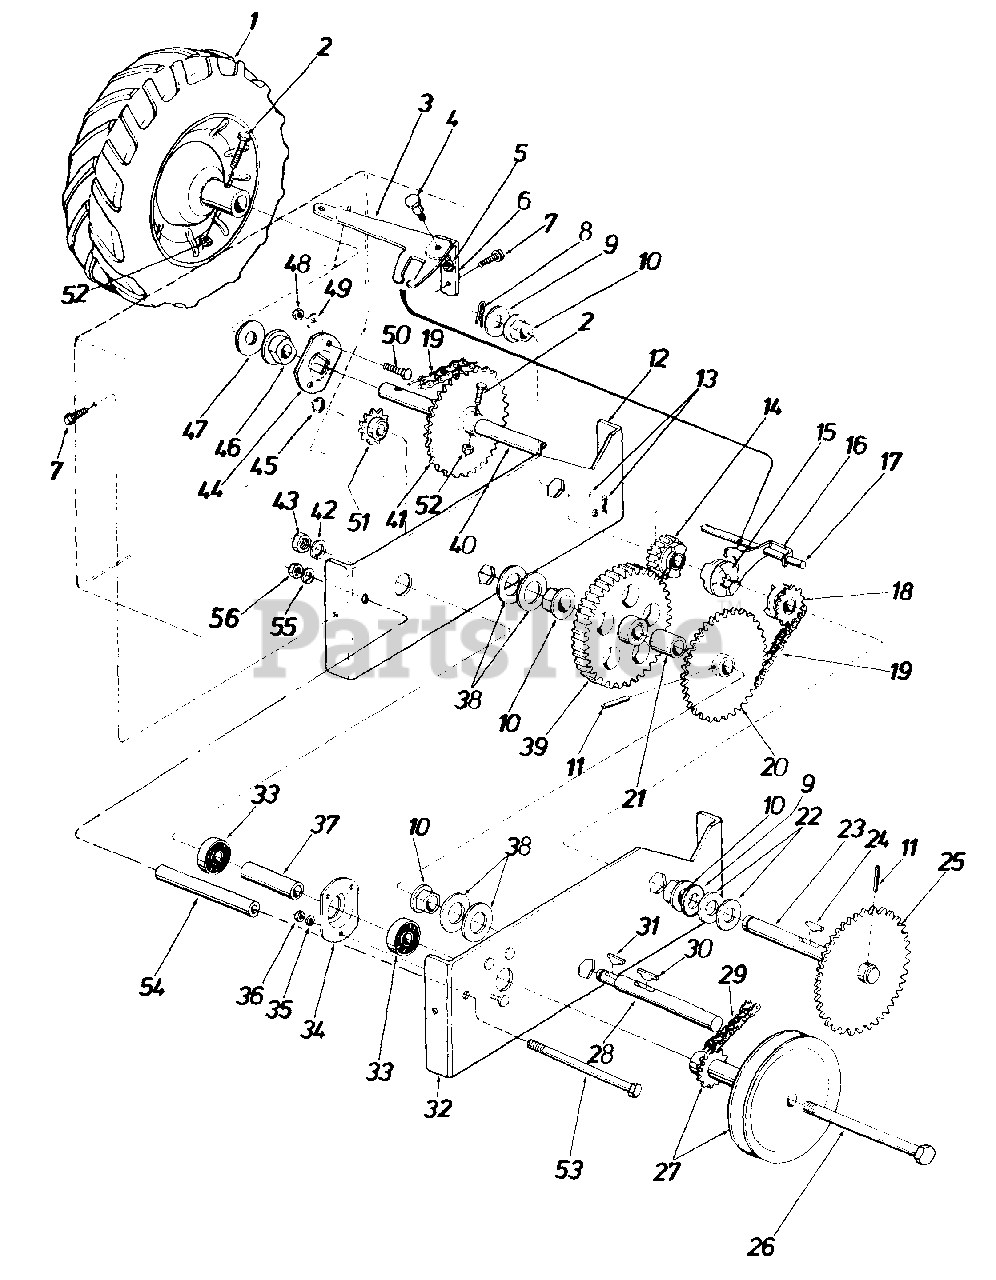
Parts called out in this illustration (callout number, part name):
1	Wheel Ass'y. - Comp. 10.0 x 2.75 - R.H.
2	Hex Scr. 5/16-24 x 1.75" Lg. H.T.
3	Shifting Bracket
4	Shld. Scr. .438" Dia. x .180 Lg.
5	Hex Cent. L-Nut 5/16-18
6	Shifting Bracket Support
7	Hex Wash. Hd. Self-Tap Scr. 5/16-24 x .50
8	Cotter Pin 3/32 Dia. x 1.00" Lg.
9	Fl-Wash. .64 I.D. x 1.25 O.D. x .060
10	Hex Flange Brg. .63 I.D.
11	H-Spring Pin Spiral 1/4" Dia. x 1.50 Lg.
12	Drive Housing Bracket - R.H.
13	Internal Cotter Pin 5/16" Dia.
14	Spur Gear - 21 Teeth
15	Clutch Collar
16	Shifting Yoke
18	Sprocket - 10 Teeth
19	#41 Chain - 1/2" Pitch x 33 Links
20	28 Teeth - Sprocket Hub Ass'y.
21	Spacer - .62 I.D. x .88 O.D. x 1.030
22	Fl-Wash. .64 I.D. x 1.25 O.D. x .100
23	Shifting Shaft
24	Hi-Pro Key 3/16 x 3/4" Dia. x 1.062
25	32 Teeth Sprocket Hub Ass'y.
26	Hex Scr. 1/2-20 x 5.50" Lg.
27	5.25" O.D. Pulley with 9 Teeth Sprocket
29	#41 Chain 1/2 Pitch x 47 Links
30	Hi-Pro Key - 3/16 x 3/4" Dia.
31	Hi-Pro Key - 3/32 x 5/8" Dia.
32	Drive Housing Bracket Ass'y. - L.H.
33	Ball Bearing .500 I.D. x 1.38 O.D. x .438
34	Bearing Housing
35	L-Wash. 1/4 Scr.
36	Hex Nut 1/4-20 Thd.
37	Spacer - .52 I.D. x .62 O.D. x 2.69
38	Fl-Wash. 1.00 I.D. x 1.75 O.D. x .100
39	Spur Gear - 62 Teeth
40	Wheel Axle
41	28 Teeth - Sprocket Hub Ass'y.
42	L-Wash. 1/2" I.D.
43	Hex Ins. Jam L-Nut 1/2-20 Thd.
44	Bearing Plate
45	E-Ring for .500" Dia. Shaft
46	Flange Bearing w/Flats .753 I.D. - Plastic
47	Fl-Wash. .81 I.D. x 1.25 O.D. x .060
48	Hex Nut 5/16-18 Thd.
49	L-Wash. 5/16" Scr.
50	Carriage Bolt 5/16-18 x .75" Lg.
51	8 Teeth Sprocket #41 Chain
52	Hex Jam L-Nut 5/16-24 Thd.
53	Hex Bolt 5/16-18 x 4.0" Lg.
54	Spacer 3.25" Lg.
55	L-Wash. 5/16" I.D.
56	Hex Nut 5/16-18 Thd.
